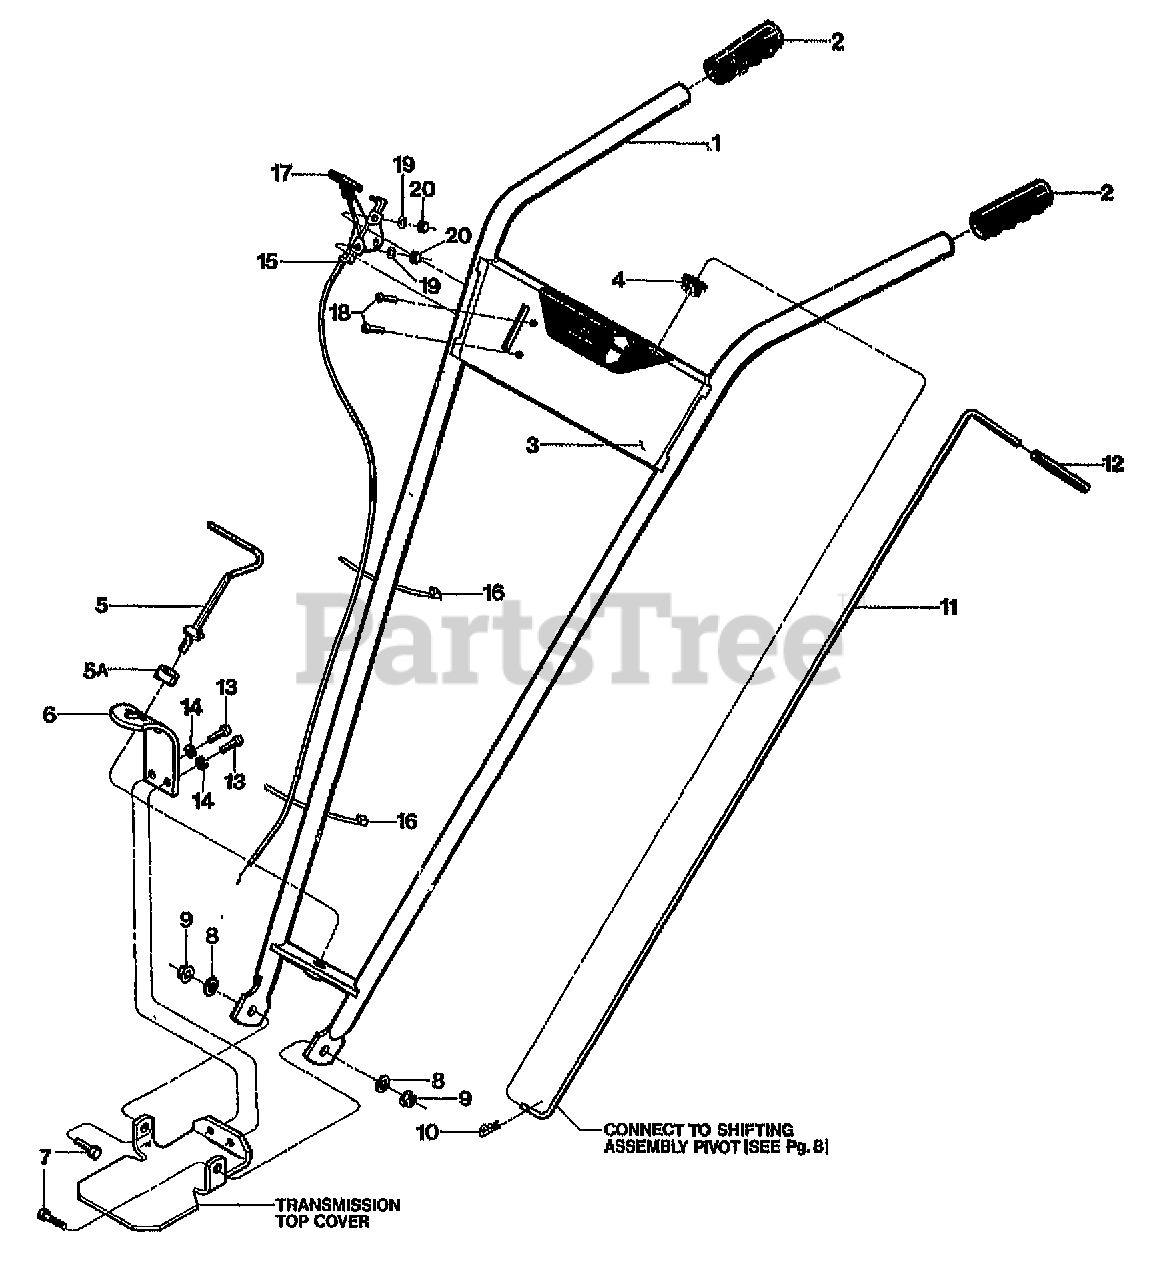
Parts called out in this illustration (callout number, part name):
1	ASSM-HANDLEBAR (Inc. 2-5A)
2	GRIP-HANDLEBAR
3	DECAL-CONTROL PANEL
4	GROMMET-PLASTIC (Part of Operator Control Panel)
5	ASSM-STUD H/B (Regulates handlebar height adj.)
5A	WASHER-1.0X.38X.375 (Keyed, used w/ #5)
6	PLATE-HANDLEBAR ADJUST
7	SCR-HH 3/8-16X1.0 G5 ZP
8	WASHER-FLAT 3/8 SAE (Handlebar adj.)
9	NUT-LOCK 3/8-16 NYLON ZP (Handlebar adj.)
10	PIN-CLIP .08
11	ASSM-DR CONTROL ROD
12	GRIP-CONTROL ROD (Forward/Neutral/Reverse Lever)
13	SCR-HH 3/8-16X.75 G5 ZP
14	WASHER-LK .375 @ DEPL
15	CABLE-THROTTLE
16	TIE-RED (To secure throttle controls cable to handlebars.)
17	KNOB-THROTTLE CABLE
18	SCR-RH M10-32X.5 MACH
19	WASHER-LK M10
20	NUT-HH M10-32X.125
